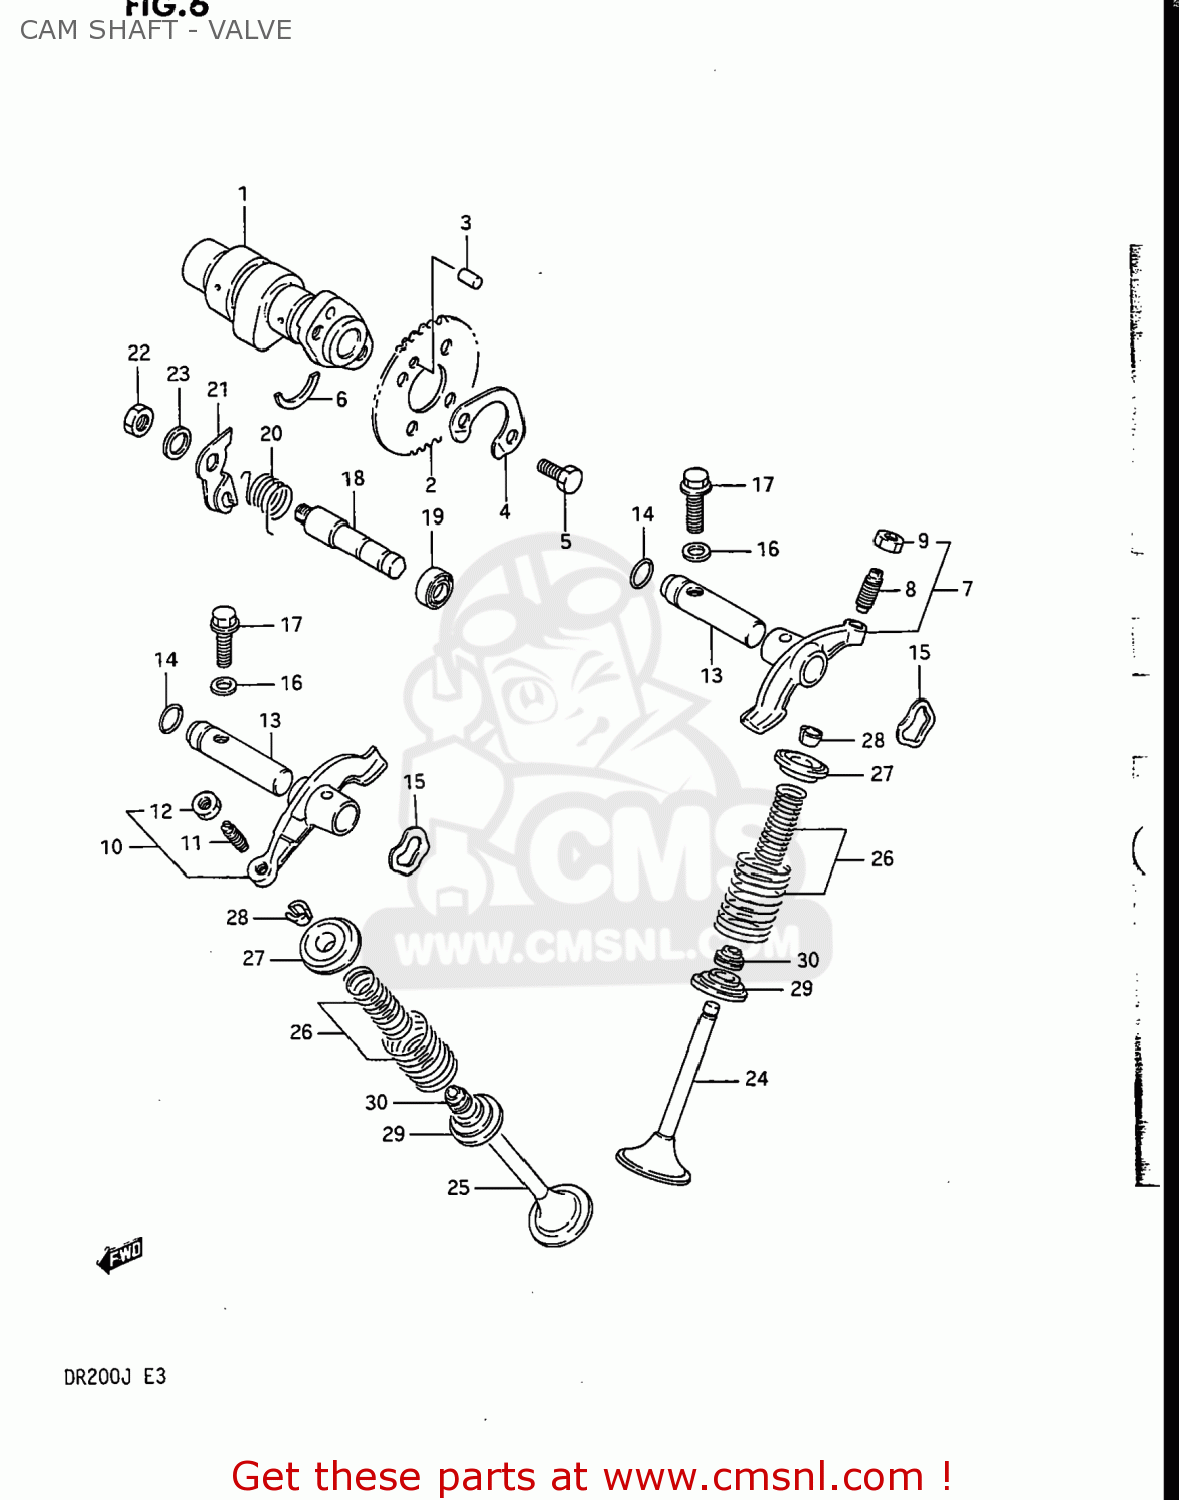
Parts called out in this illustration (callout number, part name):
1	CAMSHAFT
2	SPROCKET,CAMSHAFT
3	PIN(5X8)
4	WASHER,SPROCKET
5	BOLT(6X10.5)
6	C RING
7	ARM,VALVE ROCKER
8	SCREW,TAPPET ADJUSTING
9	NUT,ADJUSTING SCREW
10	ARM,VALVE ROCKER,EXHAUST
11	SCREW,TAPPET ADJUSTING
12	NUT,ADJUSTING SCREW
13	SHAFT,VALVE ROCKET
14	O RING(D:1.9,ID:8.6)
15	WASHER
16	WASHER
17	BOLT
18	SHAFT,DECOMPRESSION
19	OIL SEAL
20	SPRING
21	LEVER,DECOMPRESSION SHAFT
22	NUT 8MM
23	WASHER
24	VALVE,INTAKE
25	VALVE,EXHAUST
26	SPRING SET,VALVE
27	RETAINER,VALVE SPRING
28	COTTER,VALVE
29	SEAT,VALVE SPRING
30	OIL SEAL
